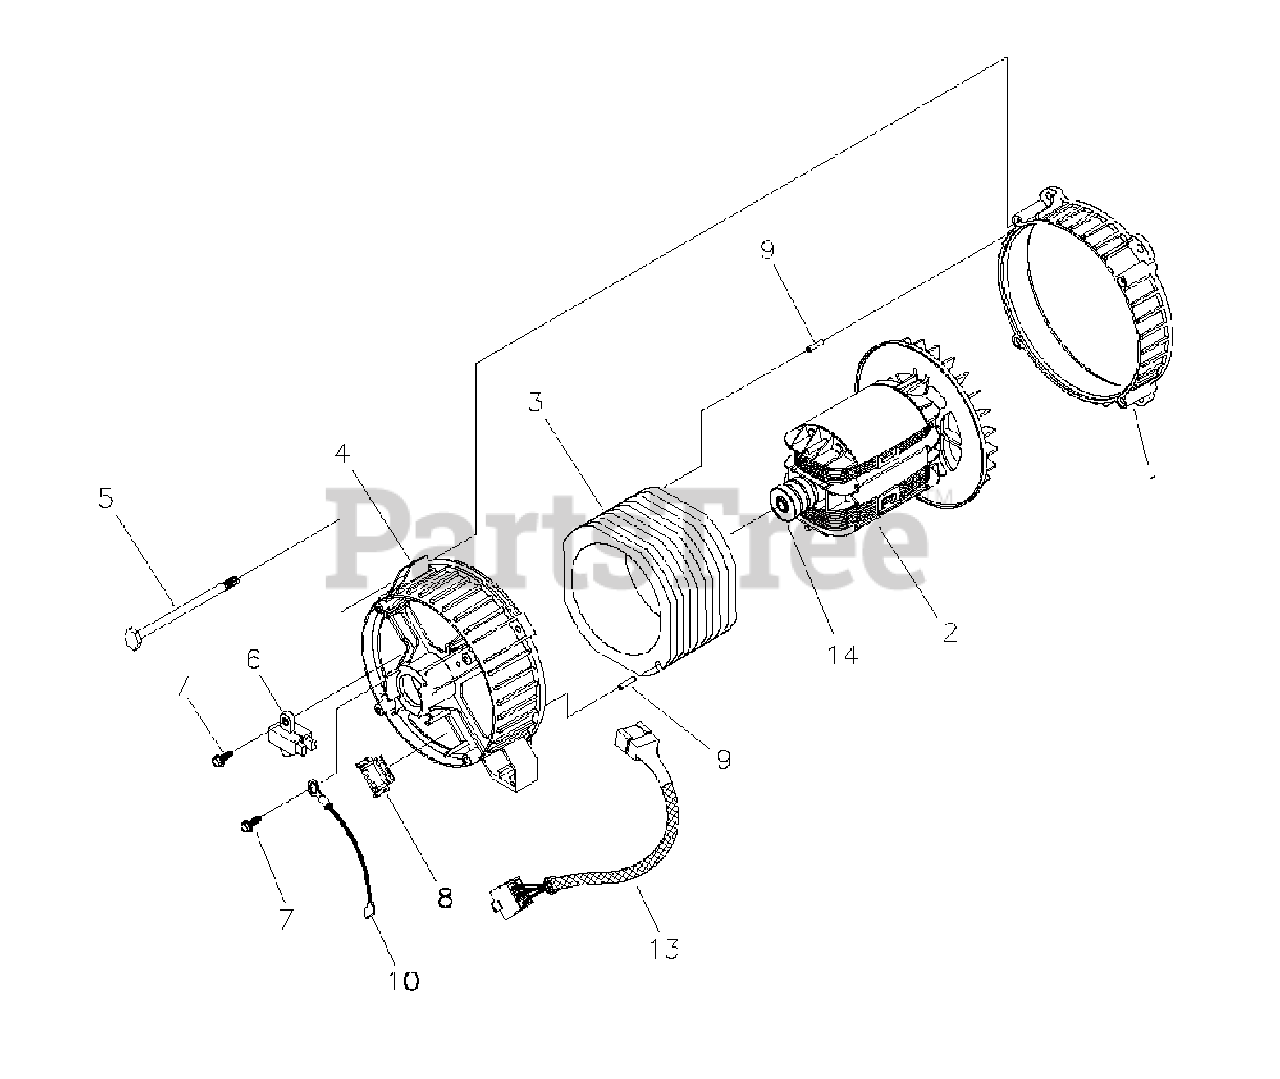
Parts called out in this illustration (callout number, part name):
1	ADAPTER, Mounting, Alternator
4	RBC, with O-Ring (p/n 189197GS)
5	HHCS, M6 - 1.0 x 115 SEMS
6	ASSY, Holder, Rectifier/Brush
7	TAPTITE, M5 - 0.8 x 16
8	RECEPTACLE, 6 pin
9	PIN, Roll, 4mm x 10
10	WIRE-ASSEMBLY, Ground
13	HARNESS, Wire, Power
14	BEARING
